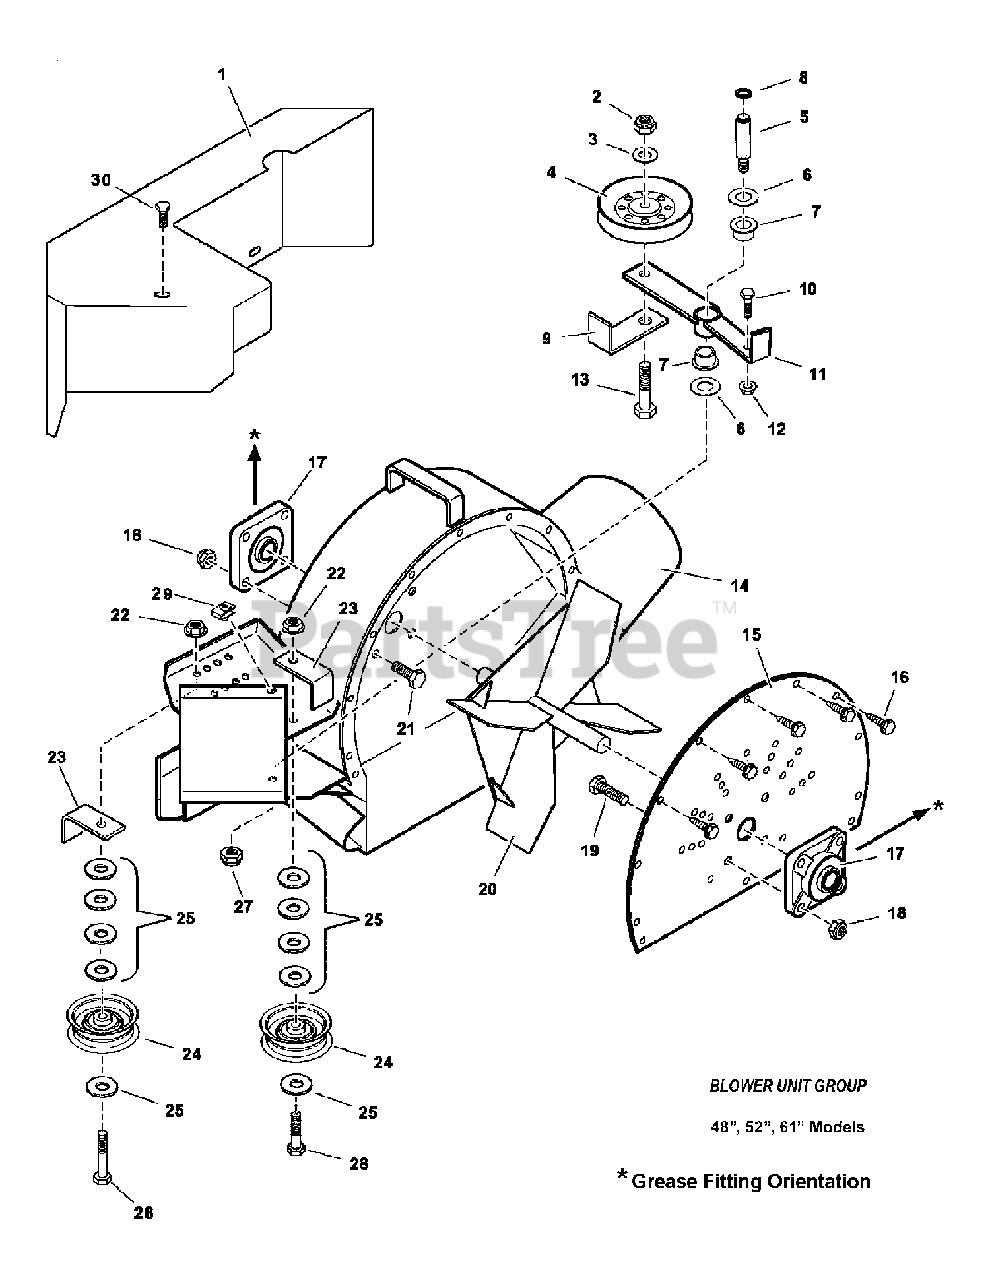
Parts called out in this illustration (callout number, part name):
1	WELDMENT, Blower Belt Guard
2	NUT, 1/2-13 Hex Nyloc
3	WASHER, 1/2" Flat SAE
4	PULLEY, A Groove Idler, Steel
5	IDLER STUD (3/8-24 thread)
6	FLAT WASHER, 9/16 Type Narrow
7	FLANGE BEARING, 9/16" I.D. (powdered metal)
8	RETAINING RING, 1/2"
9	BELT RETAINER, Idler
10	SCREW, 5/16-18 x 1-1/4" Hex Head Cap, GR5
11	WELDMENT, Idler Arm
12	NUT, 5/16-18 Hex Flange Lock
13	SCREW, 1/2-13 x 2-1/2" Hex Head Cap, GR5
14	WELDMENT, Blower Housing
15	BACK PLATE, Blower
16	SCREW, 5/16-18 x 3/4" Hex Washer Self-Tap
17	BEARING, Pillow Block, Blower (includes grease fitting)
18	NUT, 7/16-14 Hex Center Lock, GR5 or B
19	SCREW, 7/16-14 x 1-1/2" Hex Head Cap, GR5
20	IMPELLER, Fast Vac Blower (weldment)
21	SCREW, 7/16-14 x 1-1/4" Hex Head Cap, GR5
22	NUT, 3/8-16 Hex Flange Lock
23	BELT RETAINER
24	PULLEY, Flat Idler, 2-3/4" O.D.
25	WASHER, 3/8" Flat SAE
26	SCREW, 3/8-16 x 2-1/4" Hex Head Cap, GR5
27	NUT, 3/8-24 Hex Nyloc
28	SCREW, 3/8-16 x 2" Hex Head Cap, GR5
29	U-CLIP, 5/16-18
30	SCREW, 5/16-18 x 3/4" Hex Washer Self-Tap
